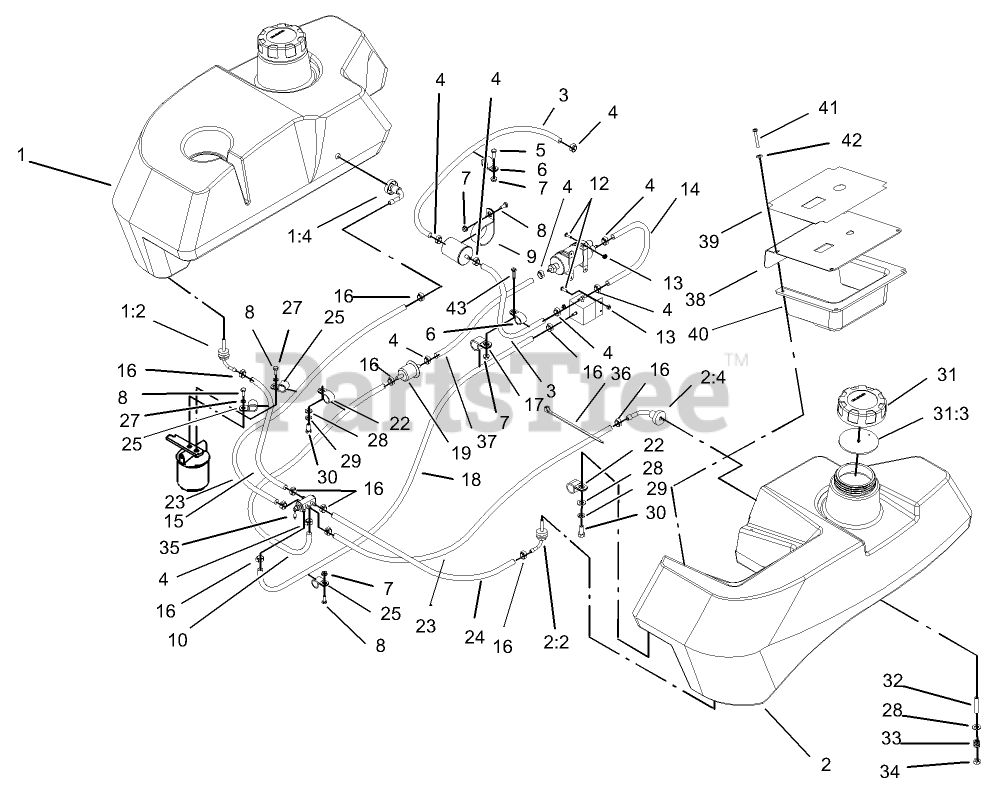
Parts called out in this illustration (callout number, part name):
1	RH Fuel Tank ASM
1:2	FITTING-FUEL, BULKHEAD
1:4	Fitting-Fuel, Bulkhead
2	LH Fuel Tank ASM
2:2	FITTING-FUEL, BULKHEAD
2:4	Fitting-Fuel, Bulkhead
3	Hose-Fuel
4	CLAMP-HOSE, FUEL
5	SCREW-HH
6	CLIP-LOOM
7	NUT-HF
8	SCREW-HH
9	CLIP-LOOM
10	HOSE-FUEL
12	SCREW-PPH
13	NUT-LOCK, NI
14	Hose-Fuel
15	Hose-Fuel
16	CLAMP-HOSE, FUEL
17	CLIP-LOOM
18	Hose-Fuel
19	Connector
23	HOSE-FUEL
24	HOSE-FUEL
25	CLIP-LOOM
27	WASHER-LOCK
28	WASHER-PLAIN
29	WASHER-LOCK
30	SCREW-HH
31	GAS CAP ASM
31:3	GASKET-CAP, GAS
33	SPRING-TANK, FUEL
34	NUT-LOCK, NI
35	VALVE-FUEL, DUAL FLOW
36	TIE-CABLE
37	HOSE-FUEL
38	Panel-Control
39	DECAL-PANEL, CONTROL
40	SHIELD-PANEL, CONTROL
42	WASHER-SPRING
43	SCREW-HH
